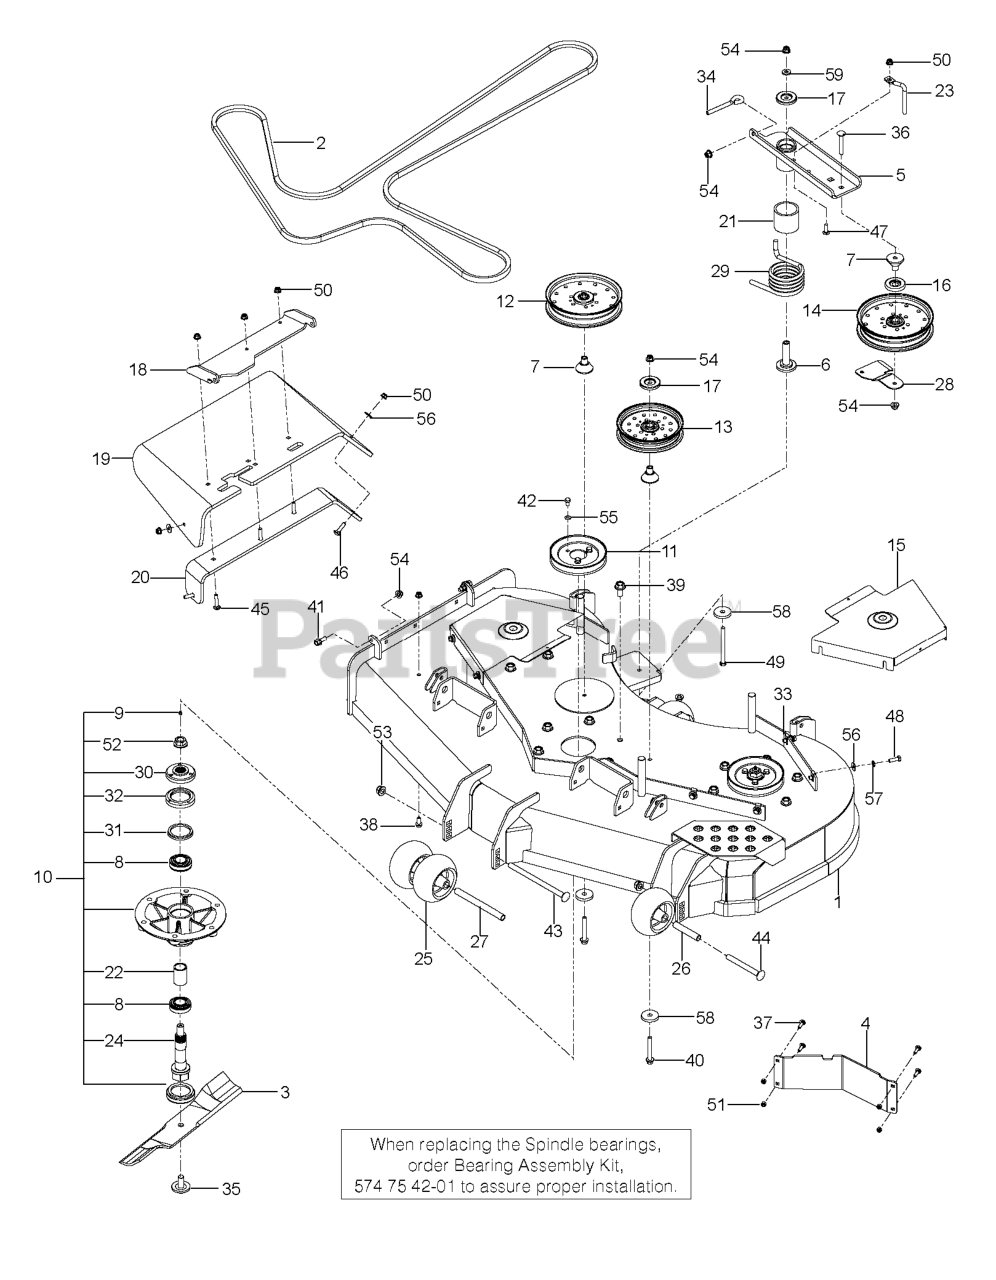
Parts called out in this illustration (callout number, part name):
1	DECK.FAB.54".W/DECALS.ORANGE
2	RP_BELT, "5V", 169.75"
3	BLADE, 19"
4	BAFFLE, DIVERTER 54"/60" LH
5	ASSY, IDLER ARM, PZ
6	BEARING, IDLER PIVOT
7	BEARING, IDLER ARM
8	BEARING - 206KRR8
9	ZERK
10	SPINDLE ASM. 10"
11	PULLEY - 5.93 OVER PINS
12	PULLEY - 7" NARROW
13	PULLEY IDLER, 6" NARROW
14	PULLEY - IDLER 7"
15	SHIELD,BELT, 60" ORANGE
16	SHIELD, DUST
17	DUST SHIELD
18	BRKT - CHUTE MTG BLACK
19	CHUTE, DISCHARGE 48-52
20	BRKT, CHUTE SUPPORT BLACK
21	SPACER, IDLER PIVOT
22	SPACER - BEARING
23	BELT KEEPER
24	SHAFT - SPINDLE
25	ROLLER, GAUGE .635 BORN
26	TUBE, ROLLER AXLE
27	TUBE, ROLLER AXLE LONG
28	BELT.GUIDE.BLACK
29	SPRING, TORSION, IDLER
30	HUB - PULLEY
31	V-RING, 55MM
32	CUP - DEBRIS
33	U-CLIP 5/16-18 NUT RETAINER
34	EYE BOLT, 3/8 X 4"
35	BLADE BOLT/WASHER
36	CARRIAGE BOLT 3/8-16 X
37	1/4-20X3/4 CARR BLT
38	HHFS 5/16-18 X 3/4
39	HHFS 1/2-13 X 1 GR5 ZD
40	HHFS 3/8-16 X 2-3/4 GR5 ZD
41	HHFS 3/8-16 X 1 GRD 5 ZD
42	HCS 5/16-18 X 1/2 GR 5 ZD
43	RHSNB 1/2-13 X 8 GR5 ZD
44	RHSNB 1/2-13 X 4.75 GR5 ZD
45	RHSNB 5/16-18 X 1-1/2 GR 5 ZD
46	BOLT, CARRIAGE 5/16X1-1/4
47	RHSSNB 5/16C X 1.0
48	HCS 5/16C X 1
49	HCS 3/8-16 X 4-1/2 GR 8 ZD
50	5/16-18 NYLOC FLANGE NUT
51	NUT.1/4-20.HEX.NYLOC.ZD
52	NUT FLANGE 3/4-16
53	NUT, 1/2-13 HEX FLG NYLOC ZD
54	NUT 3/8-16 HEX FLG NYLOC ZD
55	WASH 5/16 DISC SPRING ZD
56	WASHER 5/16 FLAT
57	WASHER.LOCK.HVY.HLCL.SPR.5/16
58	SPINDLE WASHER
59	WASHER, 3/8 THICK
